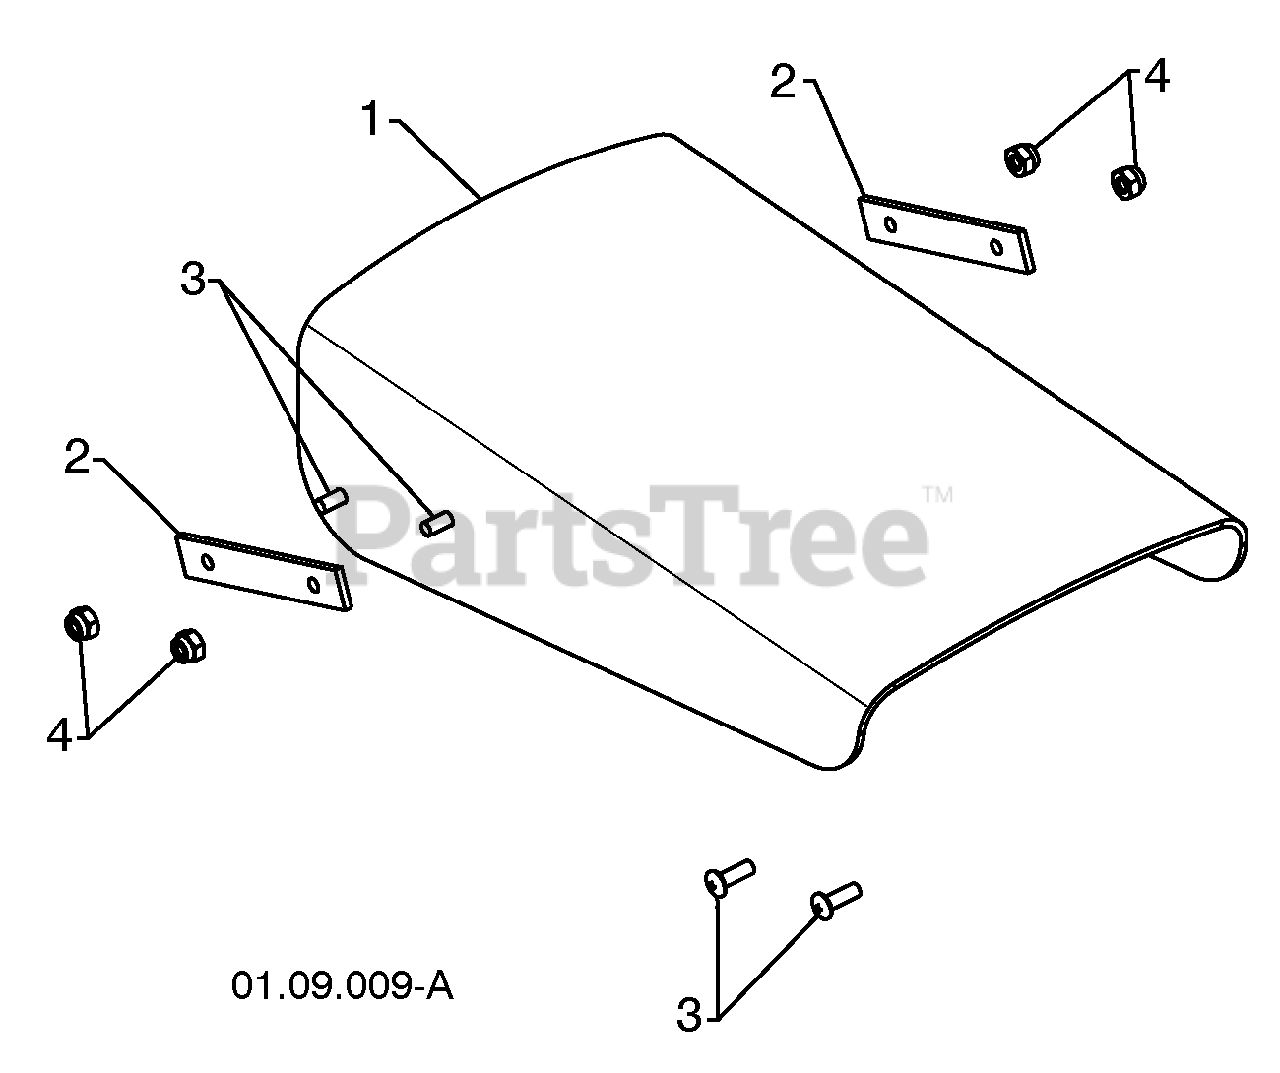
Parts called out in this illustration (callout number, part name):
1	SHIELD DEFLECTOR
2	STRAP
3	SCREW 8-32 X .50
